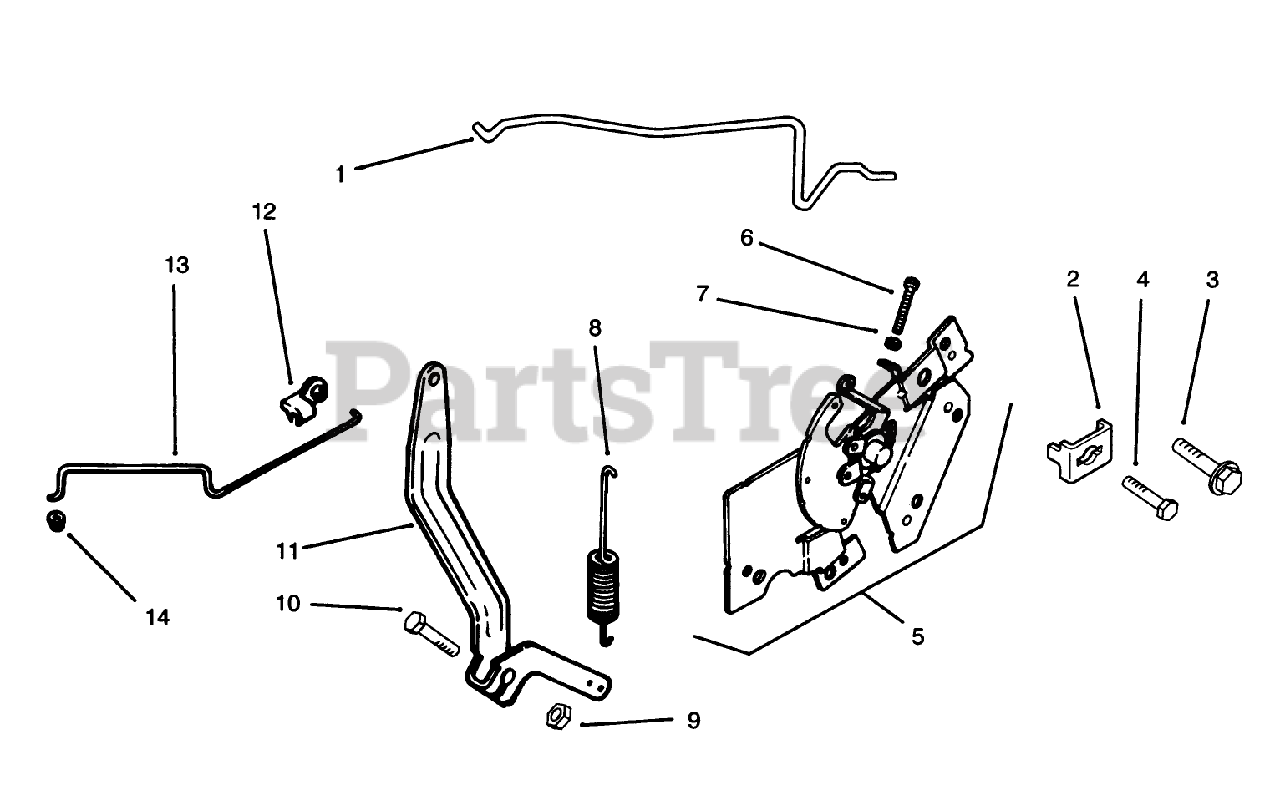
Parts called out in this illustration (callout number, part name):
1	Linkage-Choke (Only On: 72042,72043,72062,72063)
4	Screw M5x0.8x16 (Only On: 72042, 72063, 72062, 72043)
5	Control-ASM INC 6-7 (Only On: 72042, 72063, 72062, 72043)
6	Screw-HHF M4x0.7x28 (Only On: 72042, 72063, 72062, 72043)
7	Nut
8	Spring-Governor (Only On: 72042, 72063, 72062, 72043)
11	Lever-Governor (Only On: 72042, 72063, 72062, 72043)
12	Bushing-Linkage
13	Linkage-Throttle (Only On: 72042, 72063, 72062, 72043)
14	Bushing
